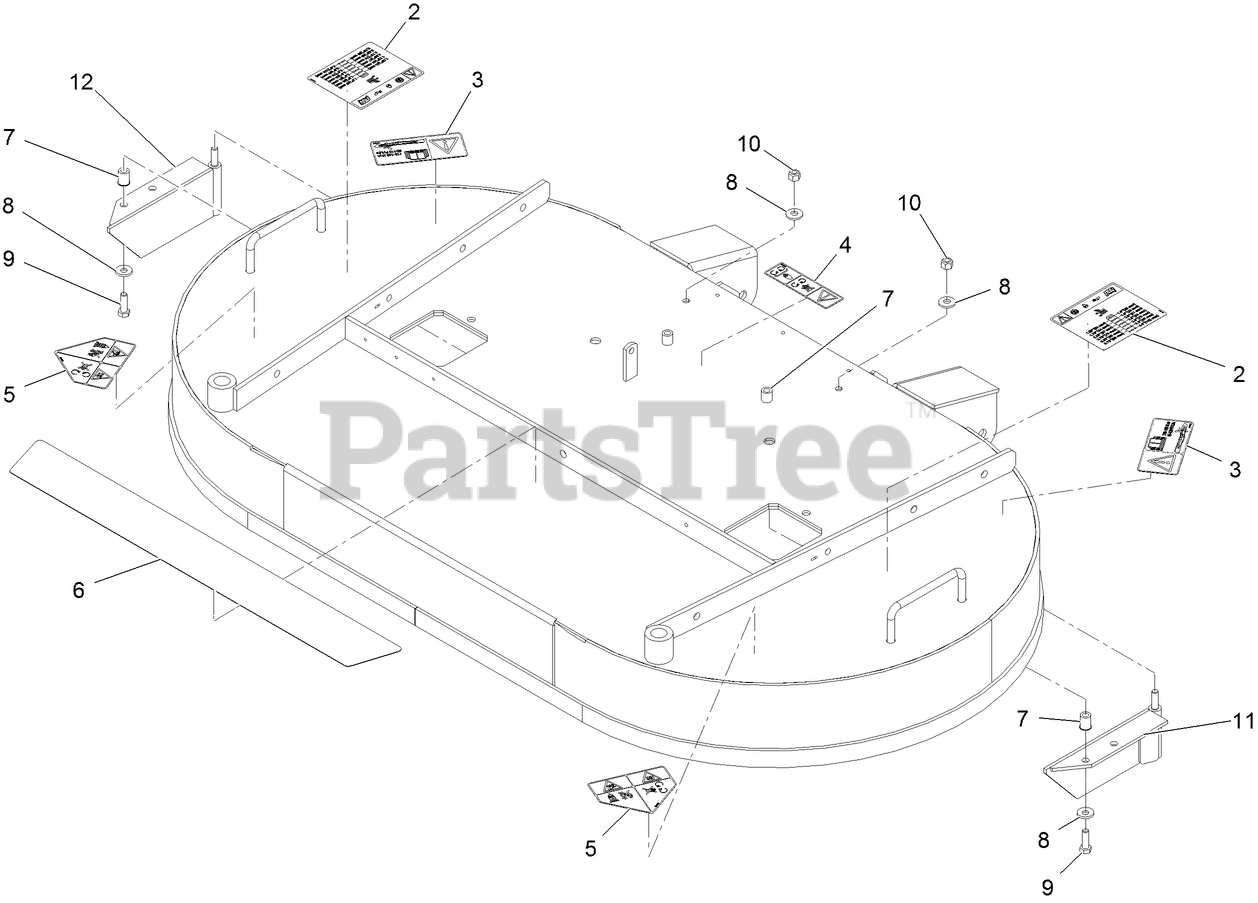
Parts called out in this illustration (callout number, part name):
2	DECAL-HEIGHT ADJUST, CUTT
3	DECAL-TORQUE, BLADE BOLT
4	DECAL-COVER, MISSING
5	DECAL-DANGER
6	PAD-ANTI SKID
7	NUT-CLINCH
8	WASHER-SPRING
9	SCREW-HH
10	NUT-LOCK, NI
11	BAFFLE-LH
12	BAFFLE-RH
